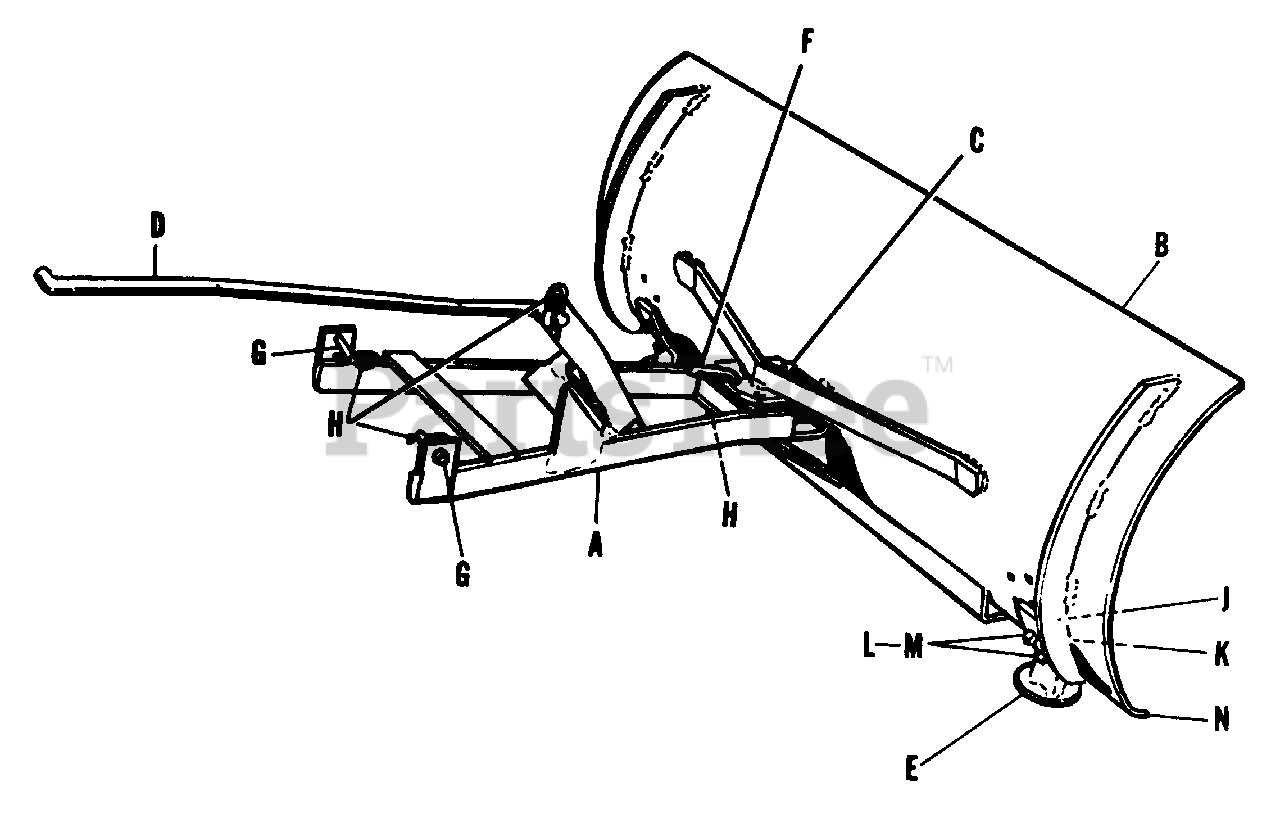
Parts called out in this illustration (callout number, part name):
A	Push Bar Assembly
B	Blade Assembly, 42"
C	Pin, King, 1/2" dia. x 2-1/2" lg.
D	Rod, Front Lift
E	Shoe Assembly
G	Pin
H	Clip, Spring
J	Bolt, Carriage, 3/8"-16 N.C. x 1" lg.
K	Bolt, Carriage, 3/8"-16 N.C. x 3/4" lg.
L	Washer, Lock, 3/8"
M	Nut, Hex., Full, 3/8"-16 N.C.
N	Plate, Wear
